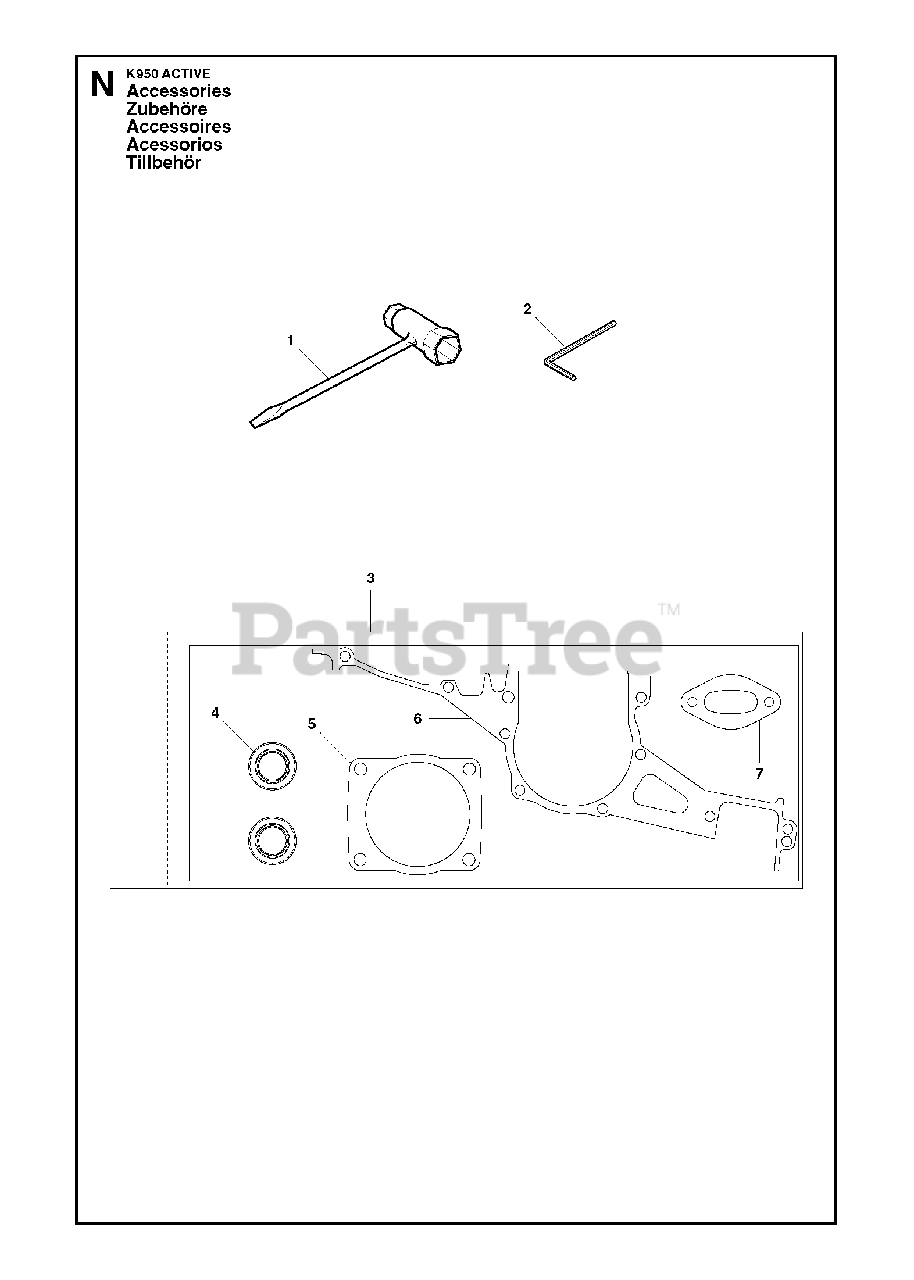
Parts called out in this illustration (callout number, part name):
1	COMBINATION WRENCH13-19mm
3	GASKET KITIncl, 4, 5, 6, 7
4	SEALING RING
5	CYLINDER BASE GASKET
7	GASKET
